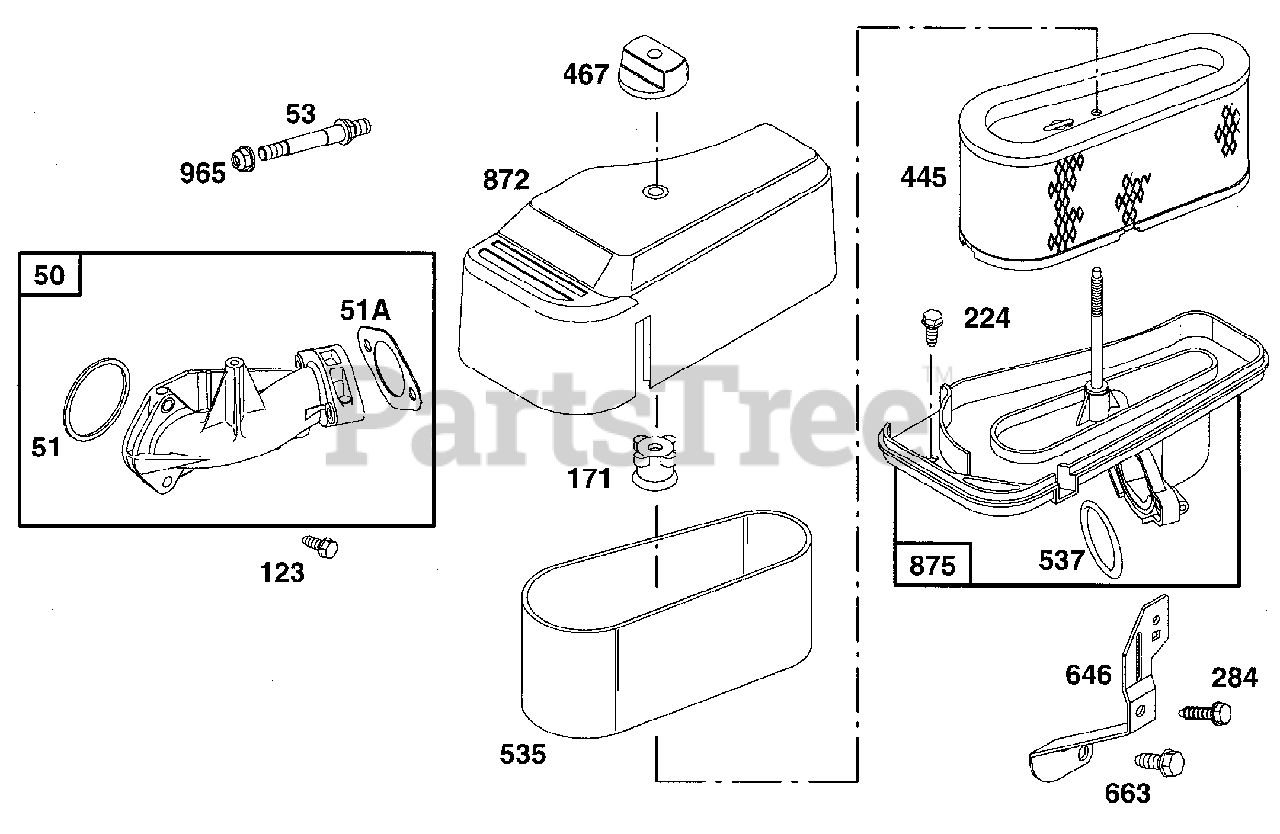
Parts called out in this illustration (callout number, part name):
50	Intake Manifold
51	Seal-O-Ring
51A	Intake Gasket
53	Carburetor Mounting Stud
123	Hex Screw
171	Air Cleaner Knob
224	Hex Screw
284	Hex Screw
445	A/C Cartridge Filter
467	Air Cleaner Knob
535	Pre-Cleaner Filter
537	Seal-O-Ring
646	Support Bracket
663	Hex Screw
872	Air Cleaner Cover
875	A/C Plastic Base
